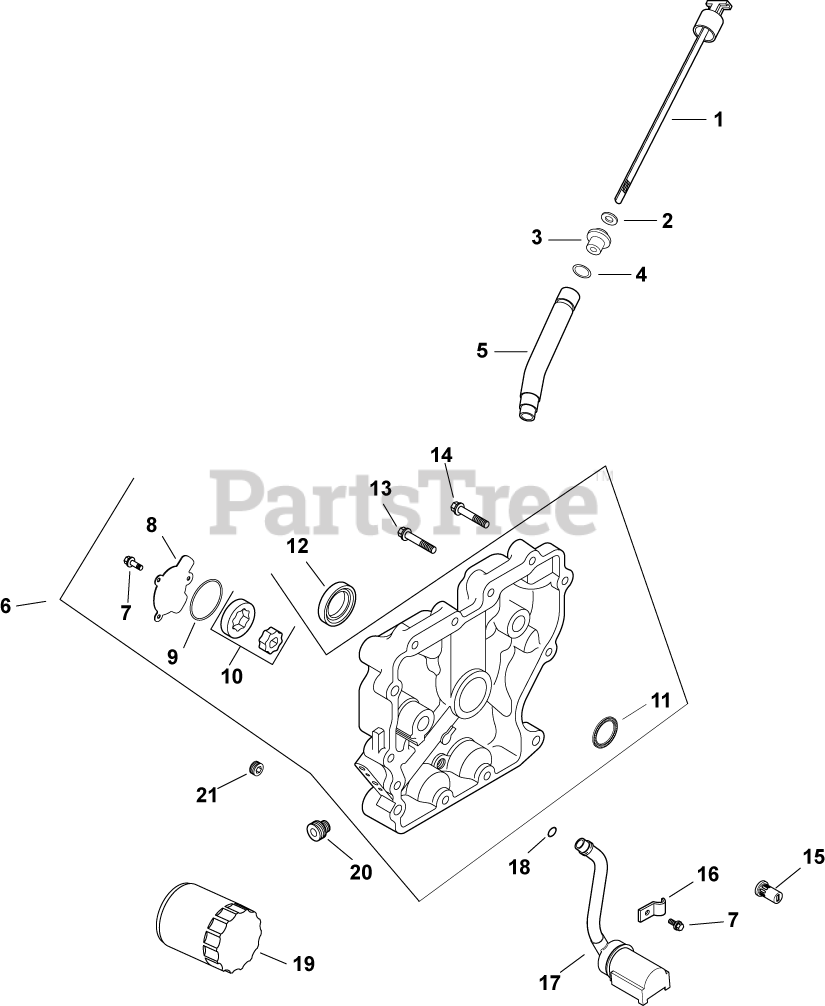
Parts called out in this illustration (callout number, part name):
3	SEAL USE 25 032 13-S
5	TUBE, OIL FILL
6	PLATE, CLOSURE & BEARING
7	SCREW,FLG THD FRM M5X0.8X16-(#25086398S)
8	COVER, OIL PUMP
9	O-RING (1.78" DIA)
10	PUMP ASSEMBLY, OIL
11	BEARING, CRANKSHAFT
12	SEAL, OIL
13	SCREW, FLG M8X1.25X45
14	SCREW, HEX FLANGE -USE 24 086 17-S
15	WASHER, FLAT
17	KIT, OIL PICK-UP
18	O-RING (.5" DIA)
19	OIL FILTER
20	NIPPLE, OIL FILTER
21	PLUG, CTSK PIPE 1/8"
